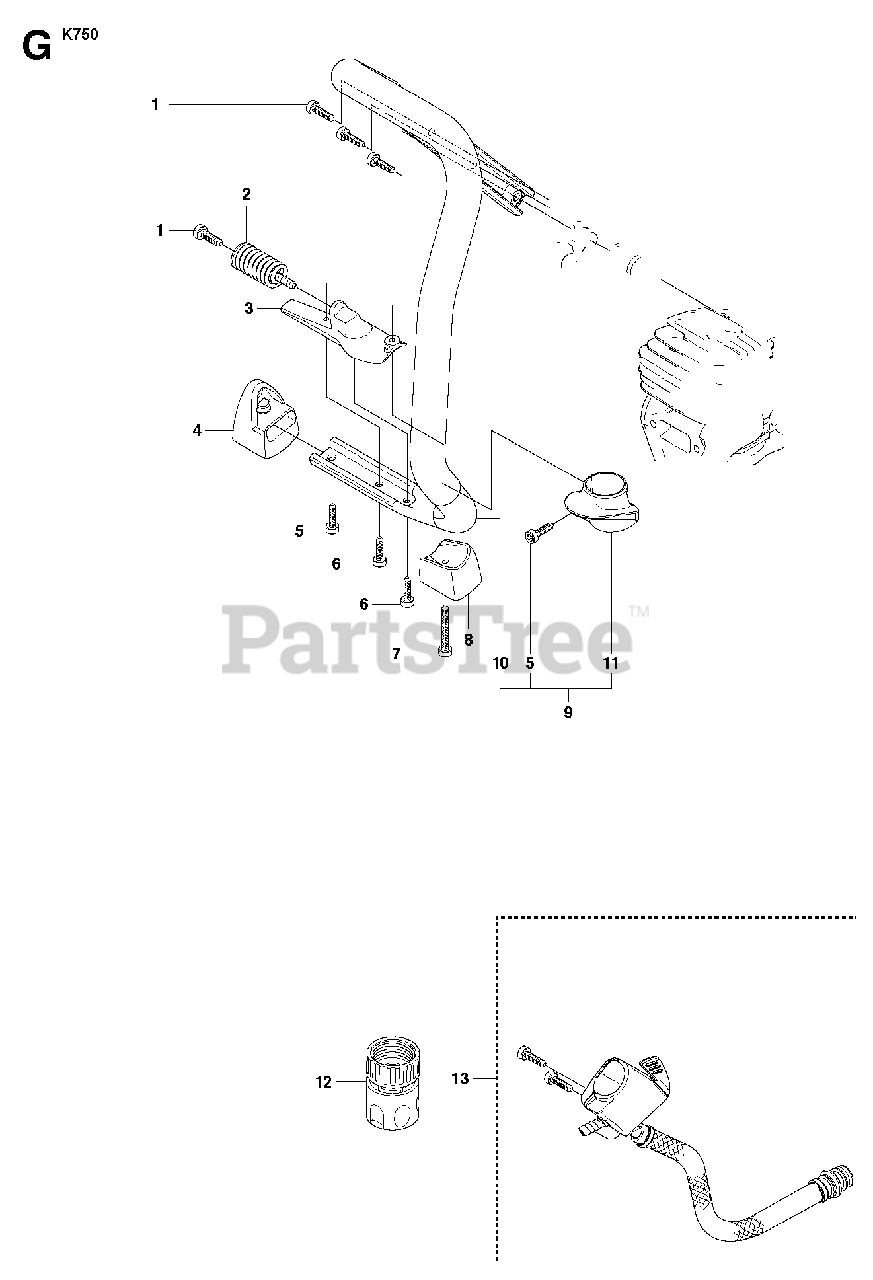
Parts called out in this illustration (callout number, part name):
1	SCREW ITXSCM
2	ANTIVIBRATION ELEMENT
3	SPRING RETAINER
4	GROUND SUPPORT
5	SCREW ITXSCT
6	SCREW ITXSCM
7	SCREW ITXSCM
8	GROUND SUPPORT
9	HANDLE
10	FRONT HANDLE
